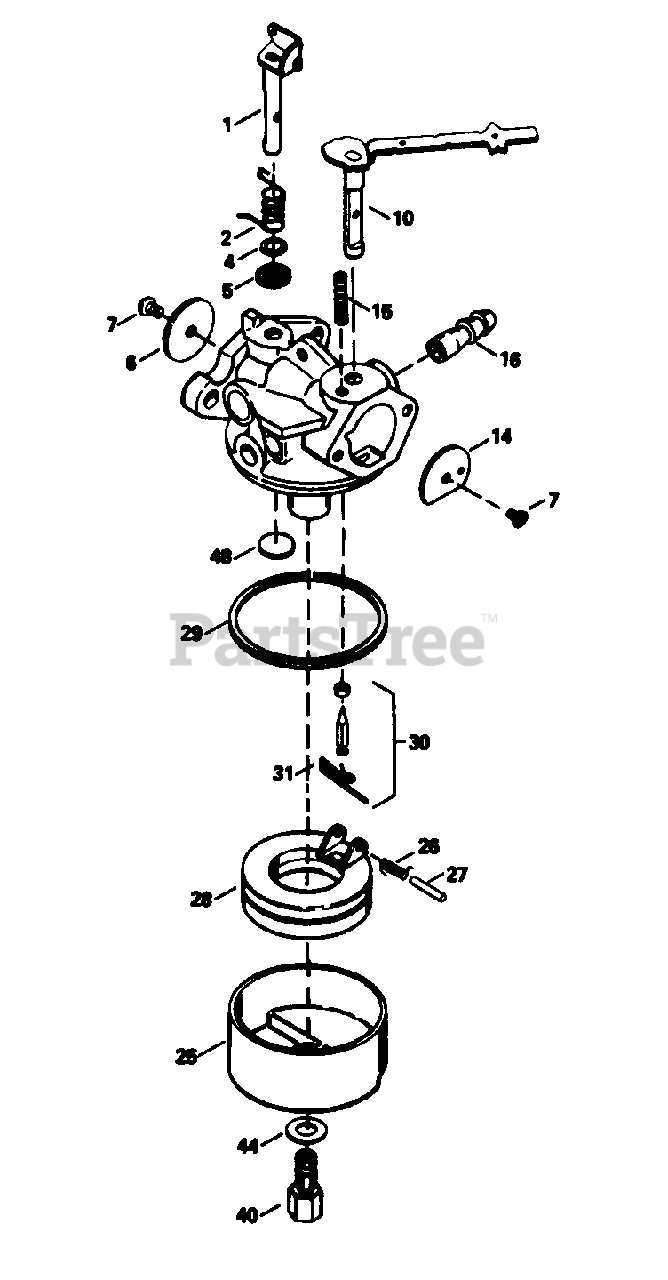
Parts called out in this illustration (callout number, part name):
1	Throttle Shaft & Lever Ass'y.
2	Throttle Return Spring
4	Dust Seal Washer
6	Throttle Shutter
7	Throttle and Choke Shutter Screw
10	Choke Shaft and Lever Ass'y.
15	Choke Positioning Spring
16	Fuel Fitting
25	Float Bowl
26	Float Dampening Spring
27	Float Shaft
28	Float
29	O-Ring, Float Bowl to Body
30	Inlet Needle, Seat & Clip
31	Spring Clip
40	High Speed Bowl Nut
44	Bowl Nut Washer
48	Welch Plug, Atmospheric Vent
